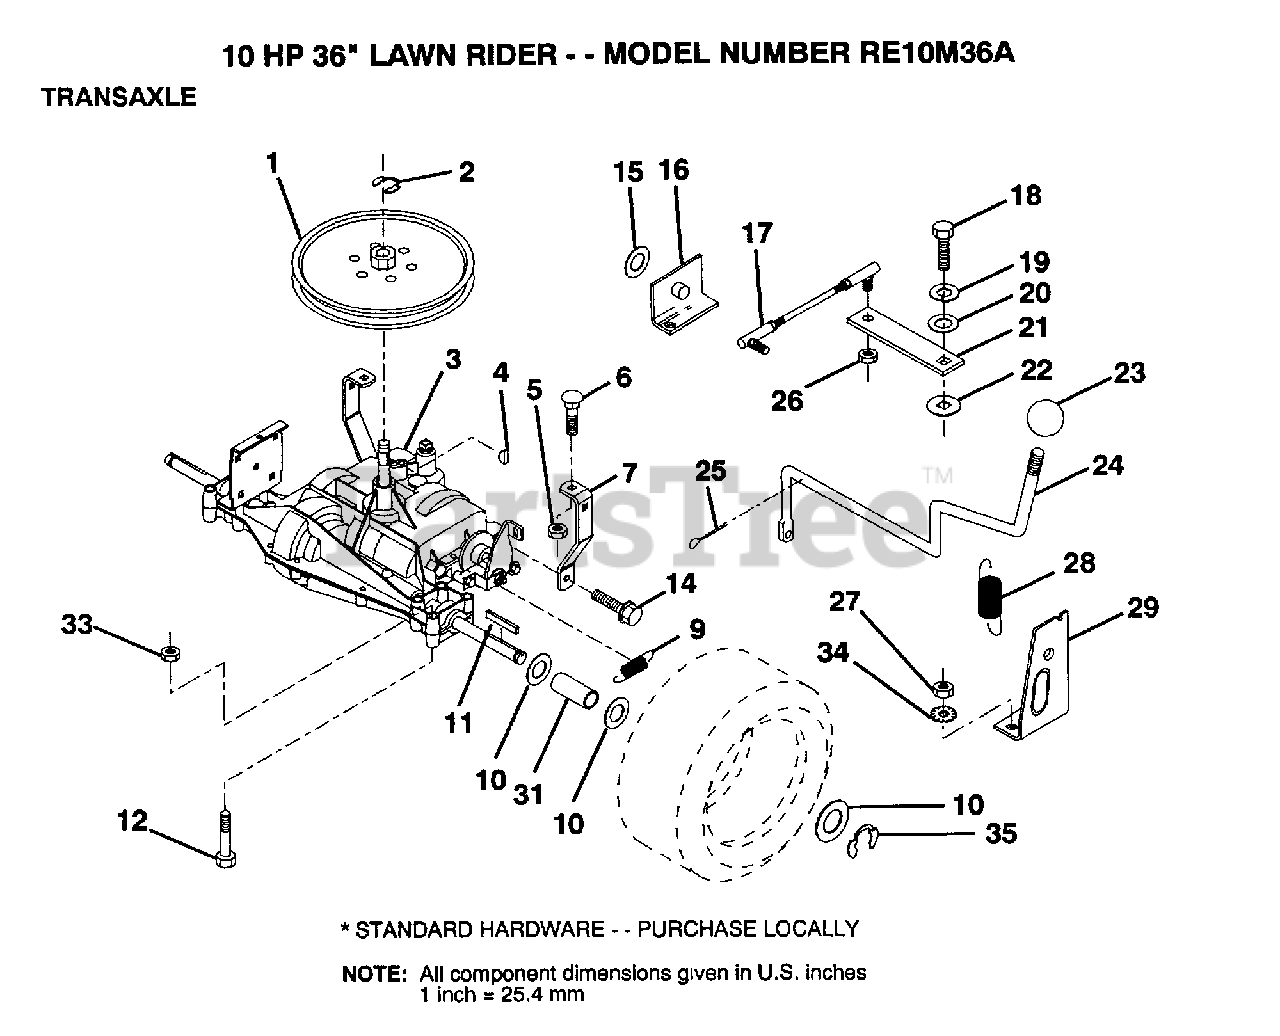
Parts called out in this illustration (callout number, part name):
1	PULLEY
6	BOLT
7	"STRAP,TORQUE"
10	WASHER
11	SQUARE KEY
12	BOLT
14	SCREW
16	"SUPT,HDLE SHT LH"
17	"LINK,SHIFT"
19	LOCKWASHER
20	WASHER LT
21	ARM SHIFT
22	WASH-SHFT PLT LT
23	KNOB T (1/2-HOLE)
24	"ROD,SHIFT"
25	PIN COTTER 1/8
26	NUT.LOCK.5/16-24
28	"SPRING,EXT"
29	"SUPT,HDLE RH"
31	SPACER
34	LOCKWASHER.5/16.E
35	E-RING LT
